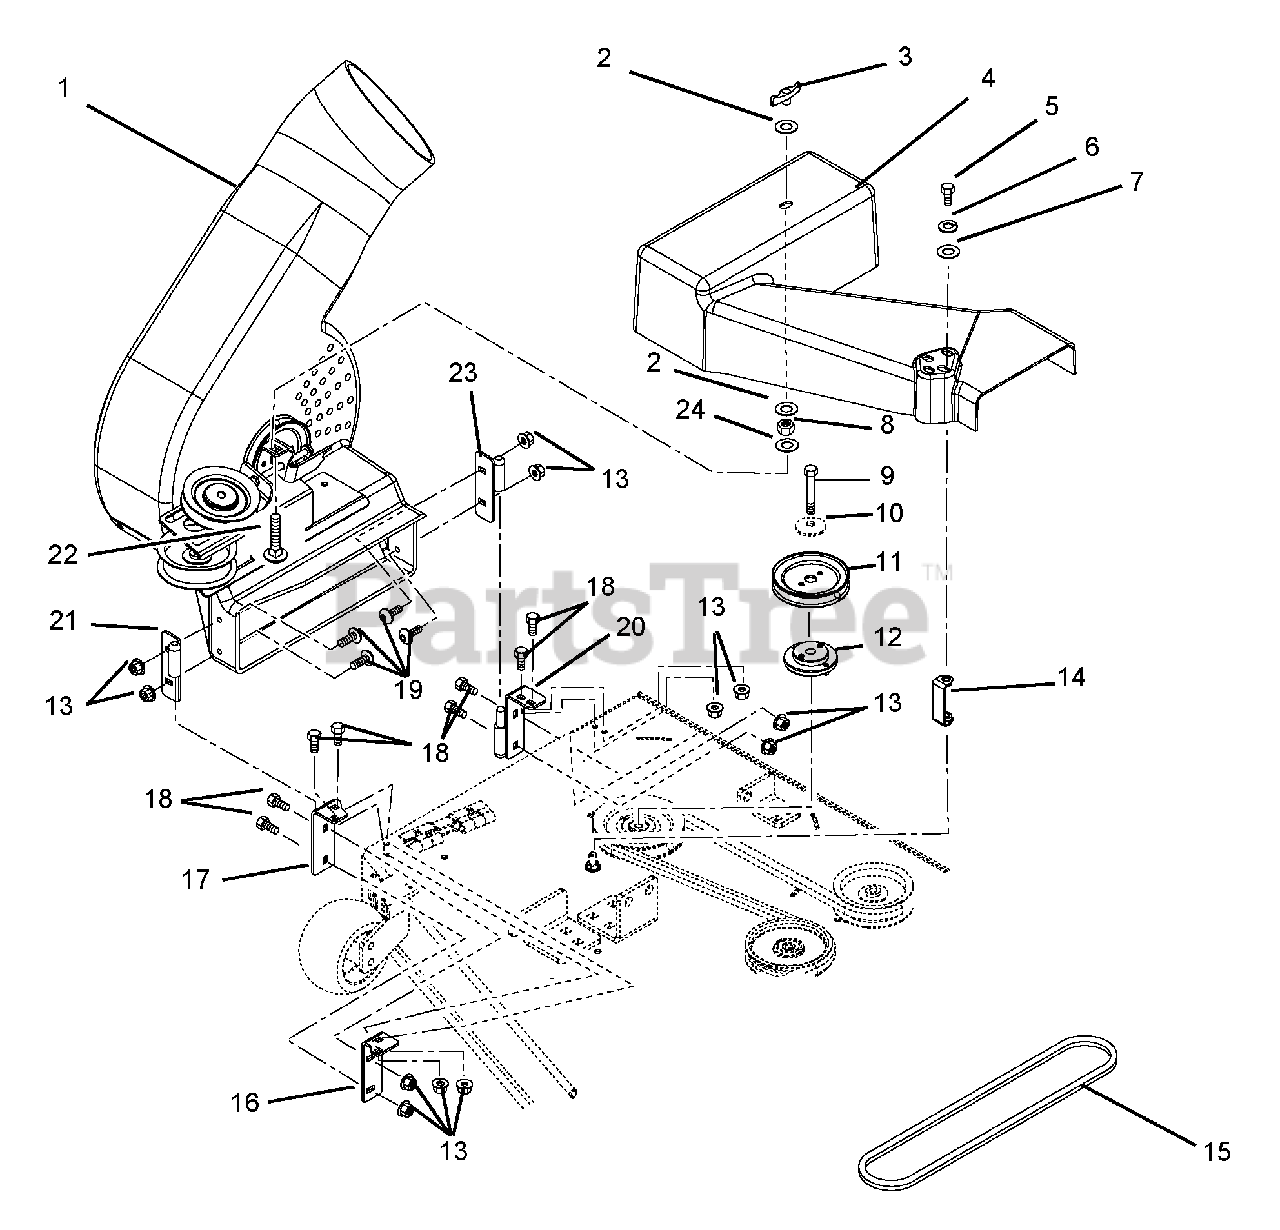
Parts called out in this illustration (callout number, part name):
1	BLOWER HSG W/DECAL
2	WSHR-FL-STL .380X1.50X.062 YWZ
3	KNOB - WING .312-18 UNC
4	BELT COVER W/DECAL
5	@BLT-HEX .38-16X.75 GR5 YWZC
6	@WSHR-LK .38X.094 REG YWZC
7	@WSHR-FL-STL.438X1.00X.083 YWZ
8	NUT- JAM .312-18 YWZC
9	BLT-HEX .38-16X1.75 GR8 M-EPYZ
10	WSHR,FLT STL.406X1.50X.245YWZC
11	SHEAVE, 3.00 DIA.
11	SHEAVE, 4.00 DIA.
12	ASSEMBLY, SHEAVE ADAPTER
13	@NUT-LK-TOP-FLG .25-20 YWZC
14	SPACER, COVER
15	V-BELT, HA-WRAPPED
16	BRACKET, FRONT
17	WELDMENT, FRONT MOUNT BRACKET
18	@BLT-HEX .25-20X.75 GR5 YWZC
19	SCR-MCH .25-20X.75 TXTR YWZC
20	WELDMENT, REAR MOUNT BRACKET
21	WELDMENT, HOUSING MOUNT RH
22	@BLT-RDHDSQNK .31-18X1.50 G5YZ
23	WELDMENT, HOUSING MOUNT LH
24	@WSHR-FL-STL.312X.734X.065 YWZ
